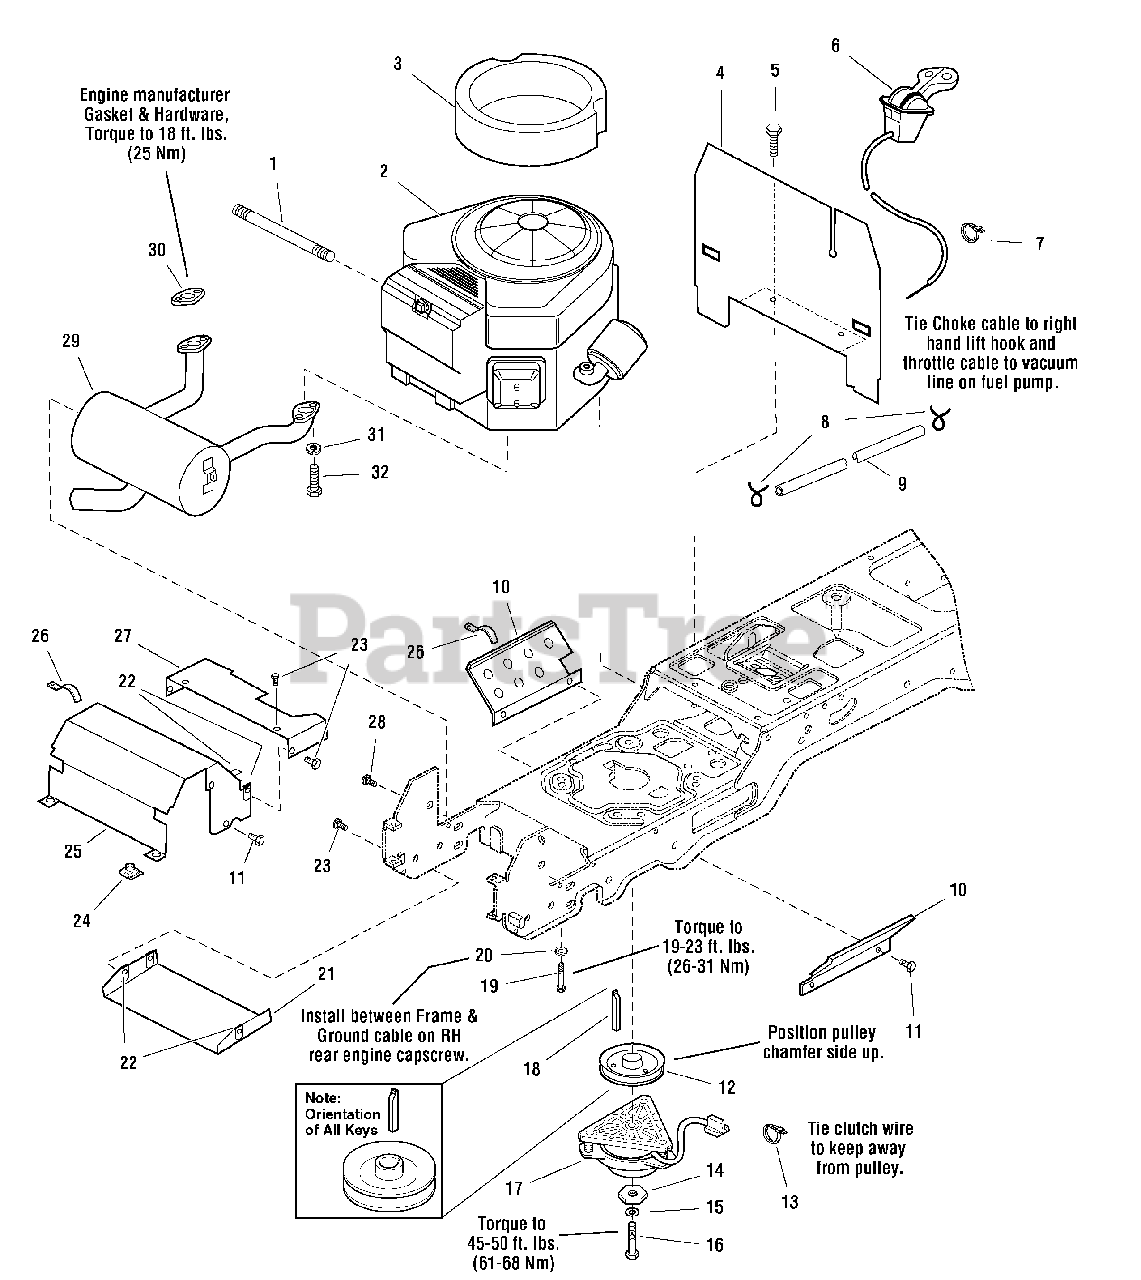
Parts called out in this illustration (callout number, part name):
1	HOSE, Oil Drain, 10 1/2 Long, 3/8-18 Fittings
3	SEAL, Circle
4	BULKHEAD
5	CAPSCREW, Hex Washer Head Taptite, 1/2-20 x 1/2, Black
6	CONTROL, Throttle Double, 39" Long
7	TIE, Self Locking
8	CLAMP, Hose Type E
9	HOSE, Fuel, 58 Long
10	SHIELD, Side
11	CAPSCREW, Hex Washer Head Taptite, 1/4-20 x 3/8
12	PULLEY & HUB ASSEMBLY
13	TIE, Self Locking
14	WASHER, Hex, 7/16, 1/4 Thick, Black
15	LOCKWASHER, Spring 7/16
16	CAPSCREW, Hex Head 7/16-20 x 3-1/2
17	CLUTCH, Electric
18	KEY, HI PRO 1/4 x 2-1/2
19	CAPSCREW, Hex Washer Head Taptite, 3/8-16 x 1-1/2
20	LOCKWASHER, External Tooth 3/8
21	SHIELD, Muffler Bottom
22	NUT, Speed, 1/4-20
23	CAPSCREW, Hex Flange Whiz Lock, 1/4-20 x 5/8
24	NUT, Speed, Lug Type, 5/16-18
25	DUCT, Muffler Top
26	CLIP, Wire 1/8, Panel
27	DUCT, Muffler Extension
28	CAPSCREW, Hex Washer Head Taptite, 5/16-18 x 1/2, Black
29	MUFFLER, Kohler Twin
30	* GASKET, Exhaust
31	LOCKWASHER, Spring, 1/4
32	CAPSCREW, Hex Flange Whiz Lock, 1/4-20 x 5/8
